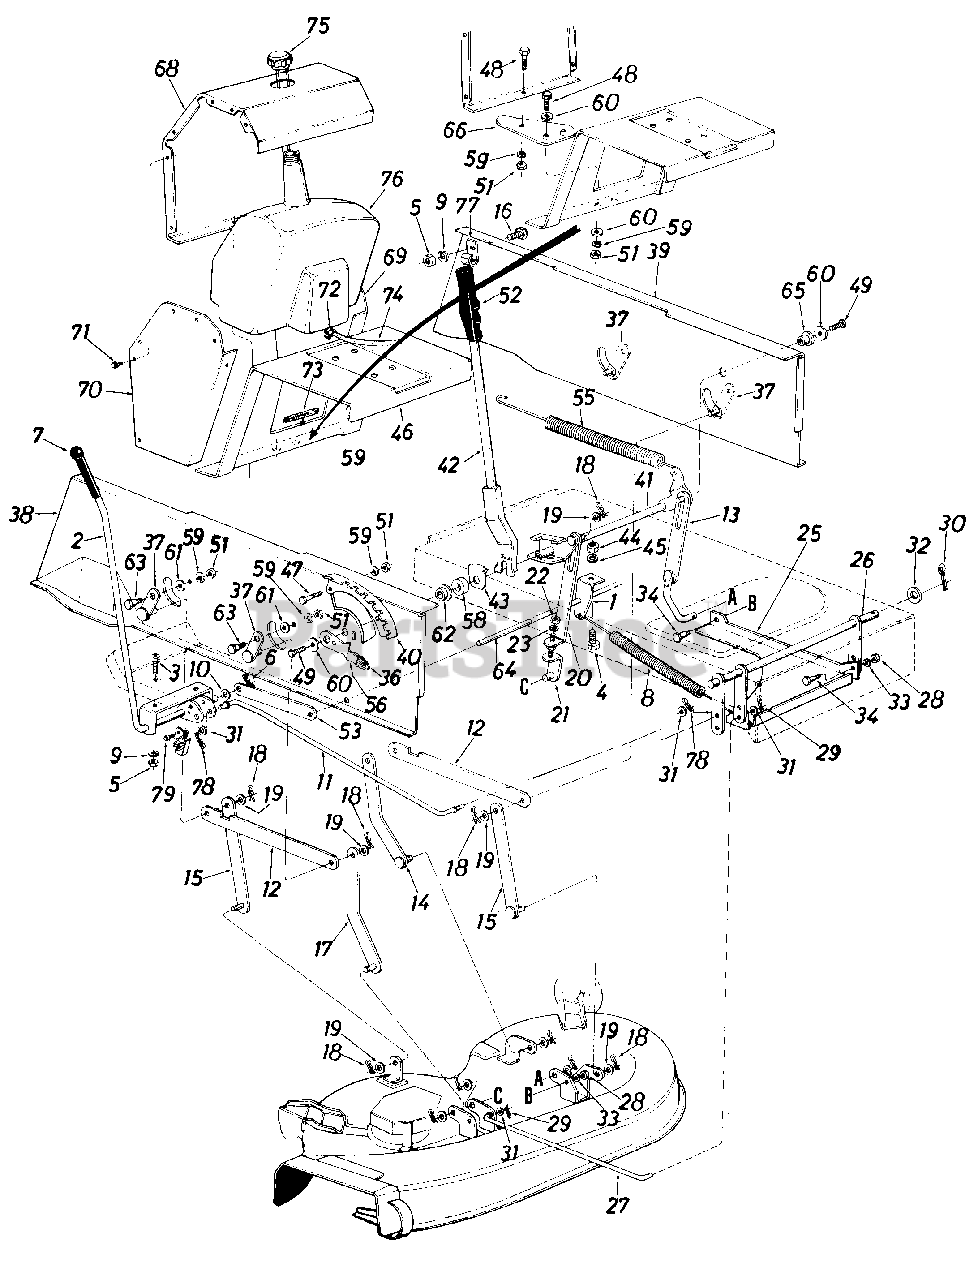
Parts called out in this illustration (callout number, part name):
1	Spring Hanger Bracket
2	Deck Engagement Lever Ass'y.
3	Truss Mach. Scr. 5/16-18 x .75" Lg.
4	Hex Bolt11/4-20 x .62" Lg.
5	Hex Nut 5/16-18 Thd.
6	Cotter Pin 3/32" Dia. x 1.00" Lg.
8	Ext. Spring .99" O.D. x 13.25" Lg.
9	L-Wash. 5/16" I.D.
10	Fl-Wash. .510" I.D. x 1.0"O.D.
11	Drive Deck Control Rod
12	Connecting Rod 3/16 x 1 x 12.5
13	Deck Lift Link Ass'y.
14	Deck Hanger Link Ass'y.-Rear L.H.
15	Deck Hanger Link Ass'y.
16	Hex Bolt 5/16-18 x .75" Lg.
17	Deck Hanger Link Ass'y.-Front R.H.
18	Inter. Cotter Pin 1/2" Dia.
19	Fl-Wash. .531 I.D. x .93" O.D.
20	Adj. Link Deck Lifting
21	Adj. Lower Link Ass'y.
22	Hex Jam Nut 3/8-16 Thd.
23	L-Wash. 3/8" I.D.
25	Diagonal Brace
26	Stabilizer Shaft Ass'y.
27	Stabilizer Rod
28	Hex Nut 3/8-16 Thd.
29	Inter. Cotter Pin 5/16" Dia.
30	Cotter Pin 1/8" Dia. x 1.25" Lg.
31	Fl-Wash. .385" I.D. x .620" O.D.
32	Fl-Wash. .635" I.D. x 1.12" O.D.
33	L-Wash. 3/8" I.D.
34	Shou Ider Bolt 3/8-16
36	Knob-Height Adj.
37	Pivot Link Ass'y.
38	Side Panel Upper Frame-R.H.
39	Side Panel Upper Frame-L.H.
40	Index Brkt.
43	Retainer Wash. Lift Handle
44	Hex Nut 1/4-20 Thd.
45	L-Wash. 1/4" I.D.
46	Hitch Plate
48	Hex Bolt 5/16-18 x 1.00" Lg. (Grade 5)
49	Hex Wash. TT-Tap Scr. 5/16-18 x .62" Lg.
51	Hex Nut 5/16-18 Thd.
52	Grip
53	Link 1.0" x 7.5" x .19
55	Ext. Spring .99" Dia. x 11.00" Lg.
56	Deck Lift-Down Stop
58	RubberWash. 1-1/2" O.D. x .63" I.D. x .6 Lg.
59	L-Wash. 5/16" I.D.
60	Fl-Wash. .344" I.D. x 1.125" O.D. x .125
61	Fl-Wash. .344" I.D. x .62" O.D. x .063
62	Flange Wash. .628" I.D. x 1.25" O.D.
63	Shld. Bolt .437" Dia. x .180
64	Running Board Rod
65	Flange Brg. .632" I.D.
66	Hitch Bar
68	Gas Tank Housing-Main Panel
69	Side Panel-L.H.-Gas Tank
70	Side Panel-R.H.-Gas Tank
71	Truss Mach. B-Tapp Scr. #10 x .50" Lg.
72	Hose Clamp-.406" Dia.
73	Trim Strip-5" Lg.
74	Gas Line-44" Lg.
75	Gas Tank Cap
76	Gas Tank
77	Hose Clamp
78	Cotter Pin 3132" Dia. x .75" Lg.
79	Hex Wash. Hd. Tap Scr. 1/4 x.50" Lg.
